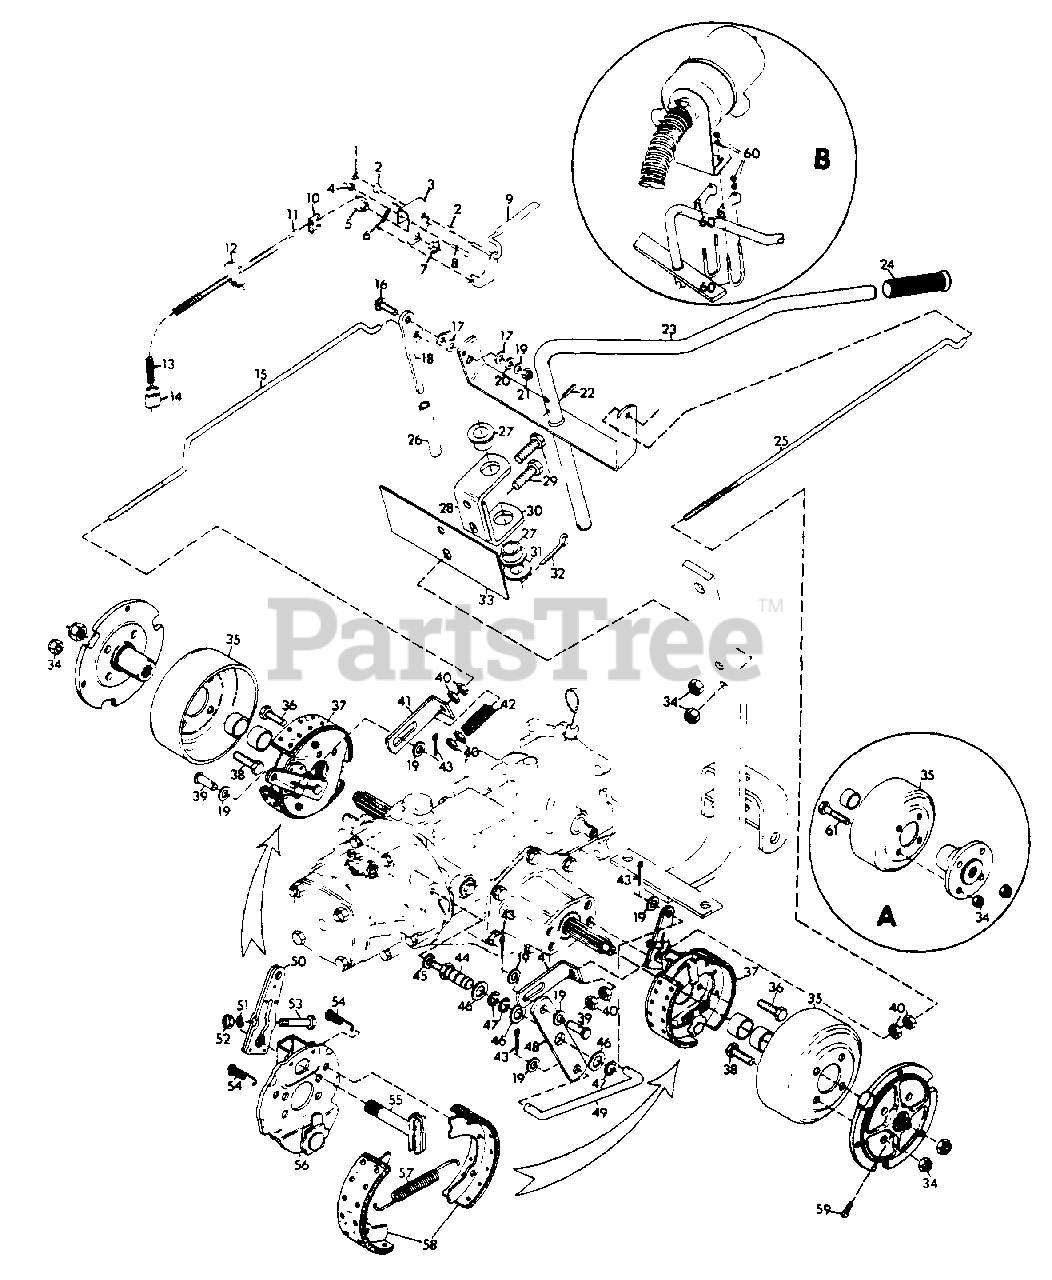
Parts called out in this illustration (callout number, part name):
1	NUT, LOCK 5/16-18
2	BUSHING, INTERLOCK LEVER
3	BRACKET, INTERLOCK MOUNTING
4	NUT, LOCK 10-24
5	SWITCH, INTERLOCK
6	SPRING, INTERLOCK
7	NUT, STAMPED 9/16-18
8	SCREW, MACH. 10-24X1.50 PHD
9	WELDMENT, HANDLE
10	CONNECTOR, 2-WIRE SWITCH
11	TERMINAL
12	TIE WRAP, BLACK
13	HARNESS, STEERING BRAKE
14	CONNECTOR
15	ROD, BRAKE
16	BOLT, 3/8-16X1.50 RD HD SQ NK
17	WASHER, NYLON .375X.75X.060
18	HANDLE, PARKING BRAKE
19	WASHER, FLAT .406X.812X.065
20	WASHER, RUBBER .375X.75X.125
21	NUT, LOCK 3/8-16
22	PIN, SPRING .31X2.00
23	WELDMENT, BRAKE HANDLEBAR
24	GRIP, HANDLEBAR
25	ROD, BRAKE L.H.
26	GRIP, BRAKE HANDLE
27	BUSHING, PIVOT
28	BRACKET, BRAKE HANDLE
29	BOLT, HEX 1/2-13X2.00
30	BRACKET, BRAKE HANDLE
31	WASHER, FLAT 1.063X2.000X.134
32	PIN, COTTER .188X1.500
33	PLATE, INSTRUCTION
34	NUT, LOCK 1/2-13
35	DRUM, 7X1.75
36	BOLT, HEX 3/8-16X.875
37	BRAKE, 7X1.75 MECHANICAL
38	BOLT, HEX 1/2-13X1.375
39	PIN, CLEVIS .375X.750
40	NUT, JAM 3/8-16
41	BRACKET, ADJUSTMENT
42	SPRING, COMPRESSION
43	PIN, COTTER .09X.75
44	STUD, PIVOT
45	WASHER, LOCK 1/2 REG.
46	WASHER, FLAT .656X1.312X.095
47	E-RING, .625 SHAFT
48	PLATE, PIVOT
49	ROD, BRAKE LINK
50	ARM, CAM LEVER
51	WASHER, LOCK 5/16 REG.
52	NUT, HEX 5/16-24
53	BOLT, HEX 5/16-24X1.75
54	SPRING, SHOE RETAINING
55	CAM, BRAKE
56	PLATE, BACK
57	SPRING, SHOE RETURN
58	KIT, BRAKE SHOE
59	SCREW, SET 7/16-14X.75 CPSH
60	CLAMP, MUFFLER
61	BOLT, HEX 1/2-13X1.625
